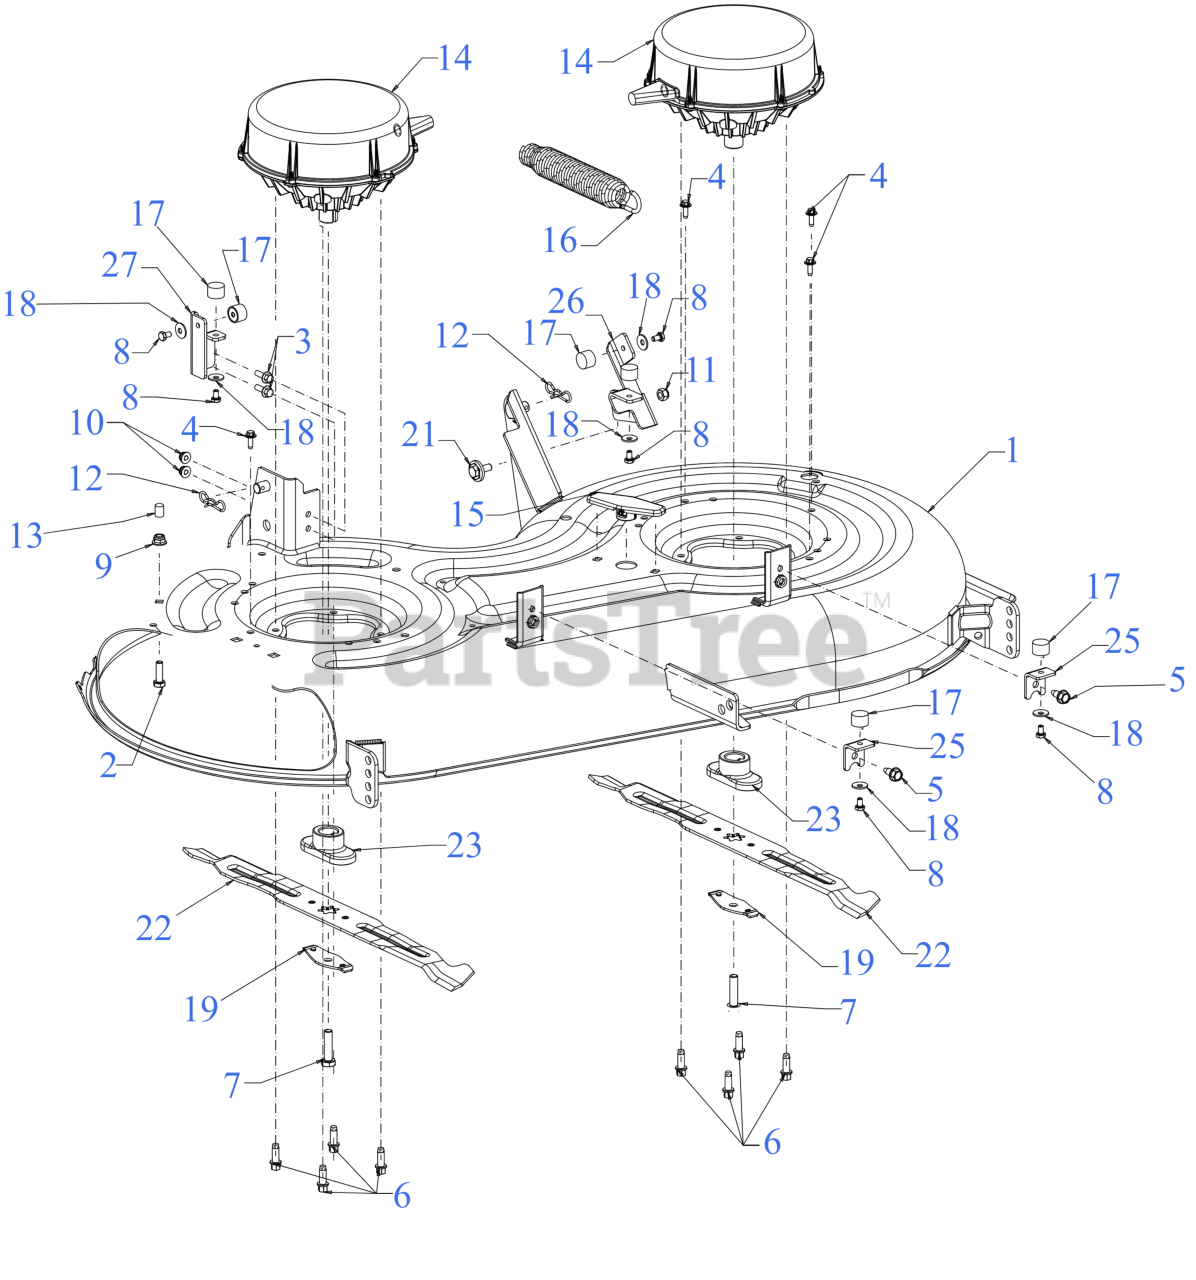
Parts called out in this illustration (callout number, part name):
1	42" DECK
2	SCREW 5/16-18 x 1.0 GR5
3	SCREW 1/4-20 x .75 GR5
4	SCREW M6-1 x .625
5	SCREW M8-1.25 x .750
6	SCREW 5/16-18 x .875
7	SCREW 3/8-24 x 1.50 GR8
8	SCREW M6-1.0X10MM GR8.8
9	FLANGE LOCK NUT 5/16-18
10	FLANGE LOCK NUT
11	HEX NUT
12	BOW TIE COTTER PIN
13	VINYL CAP
14	48V ELECTRIC DECK MOTOR
15	DECK PLUG
16	LIFT ASSIST SPRING (SMALL)
17	BUMPER
18	SPRING WASHER BELL
19	BLADE BELL SUPPORT
21	SHOULDER SCREW
22	21.18" MULCH BLADE
22	Cub Cadet 42" BLADE SET
25	UPSTOP BRACKET
26	UPSTOP BRACKET (LH)
27	UPSTOP BRACKET (RH)
